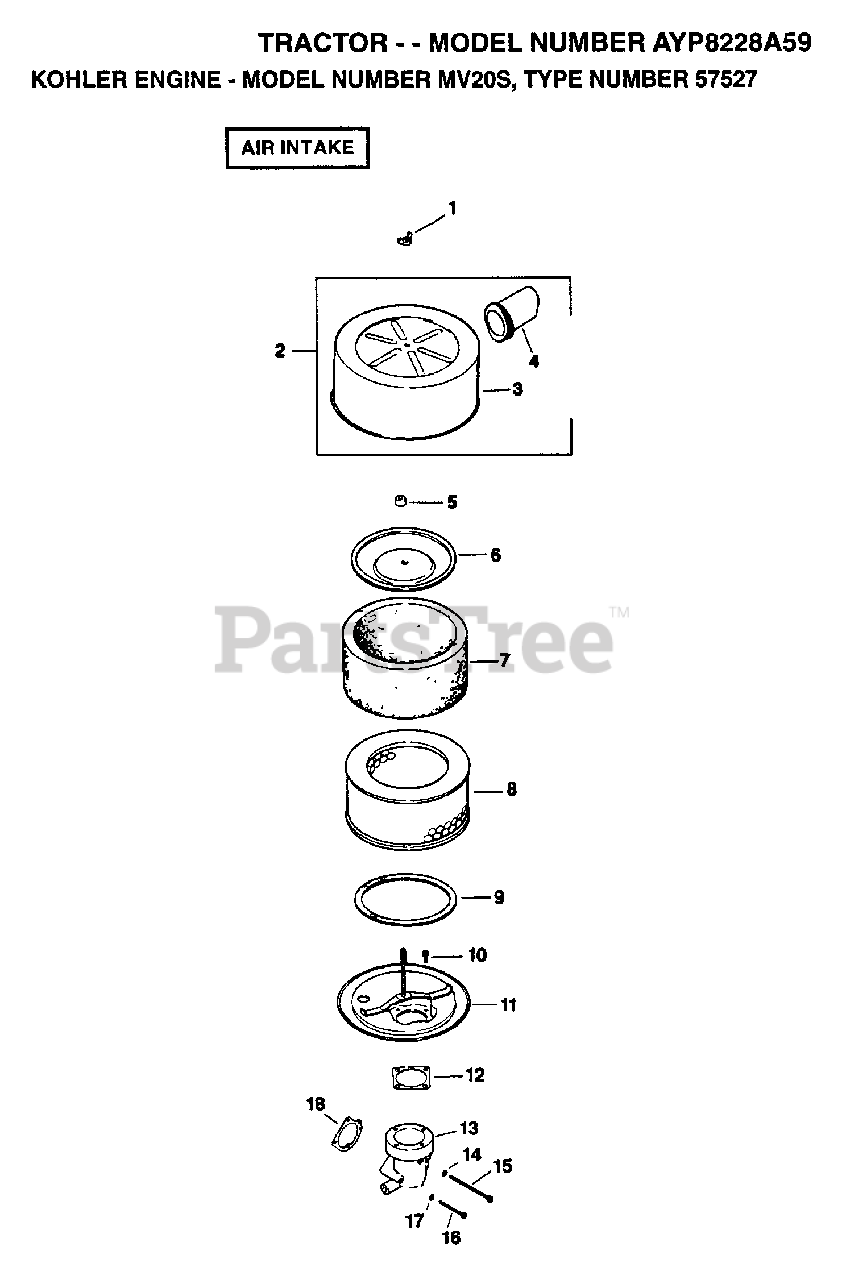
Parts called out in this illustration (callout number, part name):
1	WING NUT
3	COVER AIR CLEANER
4	TUBE AIR INTAKE
5	SEAL ELEMENT
6	COVER AIR CLEANER ELEMENT
9	SEAL
10	SCREW
12	GASKET
13	ELBOW AIR INTAKE
14	WASHER
15	SCREW
16	SCREW
17	WASHER
18	GASKET, AIR CLEANER
